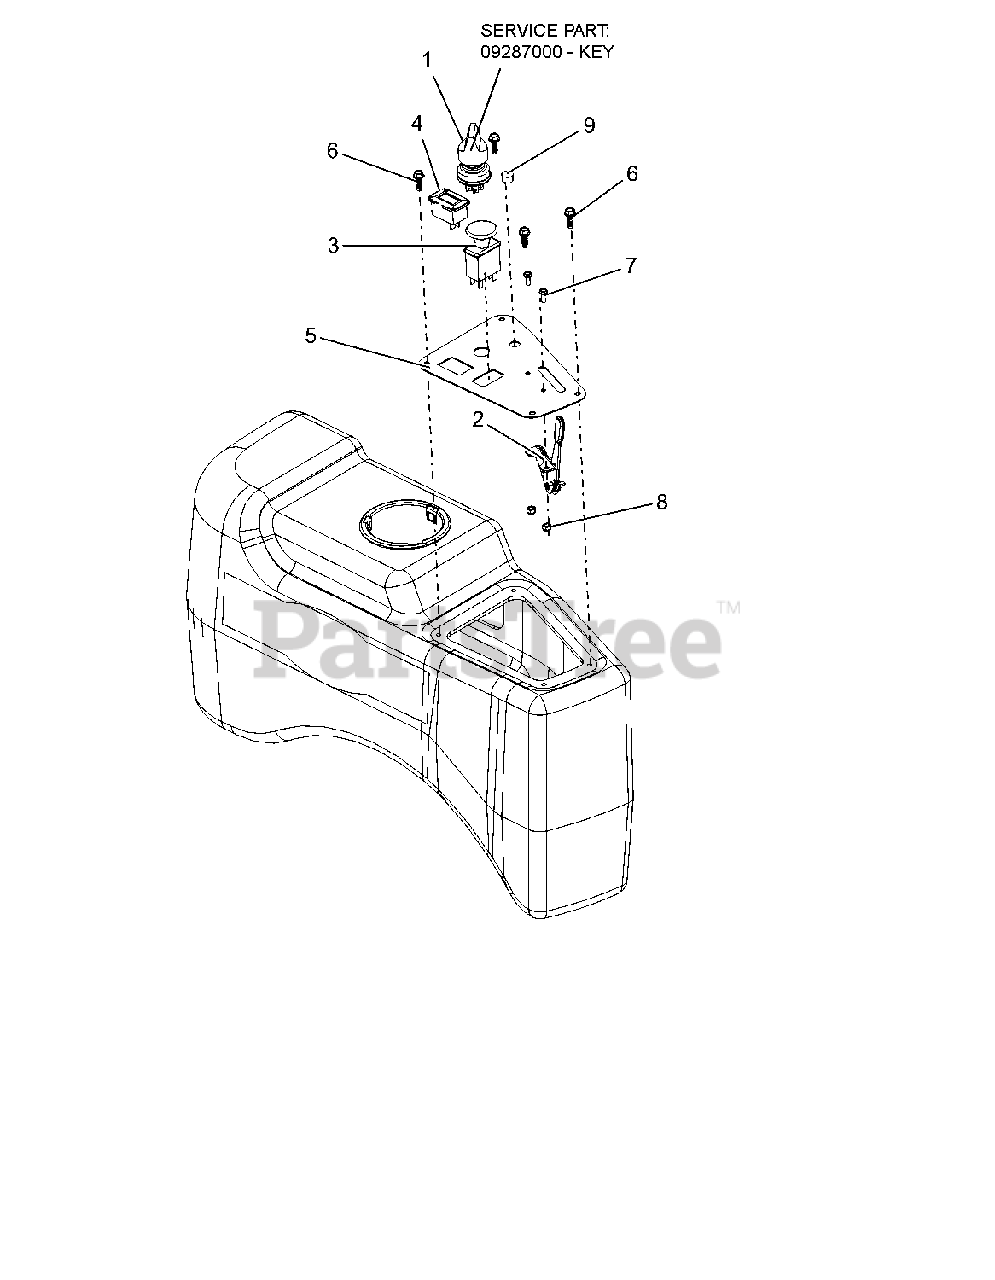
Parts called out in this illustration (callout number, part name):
1	SWITCH, IGNITION
1	KEY
2	CABLE, CONTROL
3	SWITCH, CLUTCH
4	METER, HOUR W/MAINTENANCE
5	PANEL, CONTROL
6	SCR-PLASTITE .25-10X.75 YWZC
7	@SCR-MCH 10-24X.50 HWH YWZC
8	NUT-LK-NYL #10-24 YWZC
9	PLUG, HOLE .50 DIA
